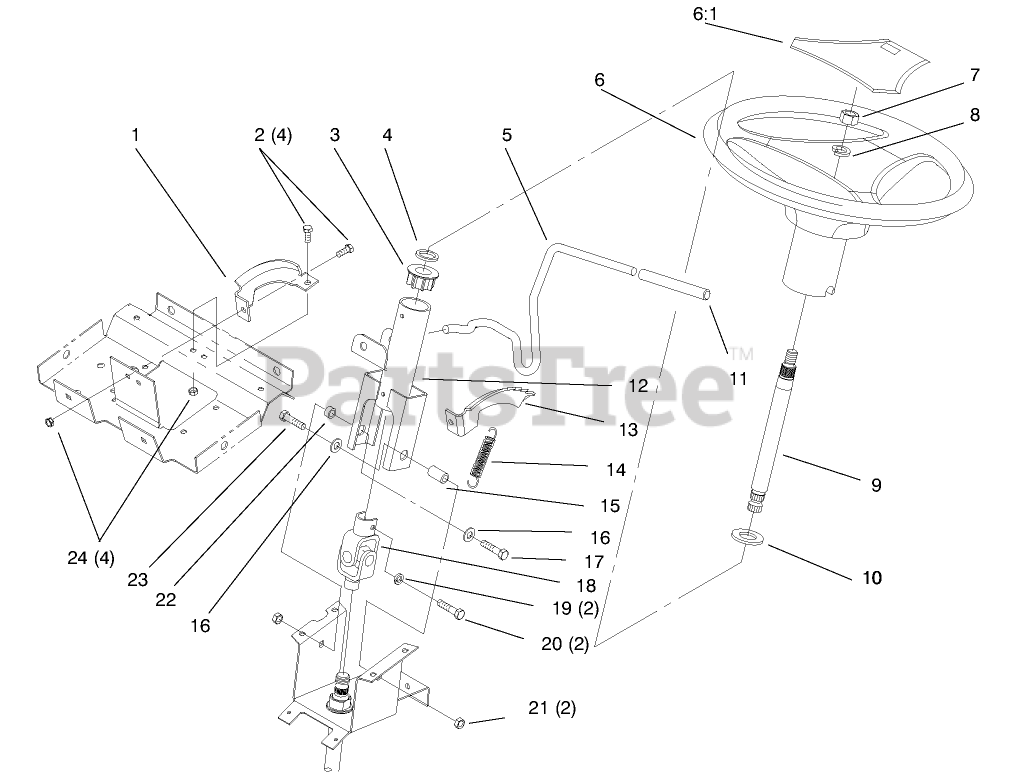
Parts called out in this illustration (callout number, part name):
1	BRACKET-SUPPORT, COLUMN
2	SCREW-HH
3	BUSHING-STEERING, UPPER
4	WASHER-BOWED
5	LEVER-TILT
6:1	COVER-WHEEL
7	NUT-HH
8	WASHER-LOCK
9	SHAFT-SHORT, STEERING
10	WASHER-FLAT
11	CAP-ROD, TILT
12	COLUMN ASM
13	BRACKET-DETENT
14	SPRING-EXTENSION
15	SPACER-YOKE
16	WASHER-PLAIN
17	SCREW-HH
18	U-JOINT, STEERING
19	WASHER-LOCK
21	NUT-LOCK, NI
22	SPACER-YOKE, RIGHT
23	SCREW-HH
24	NUT-HEX
